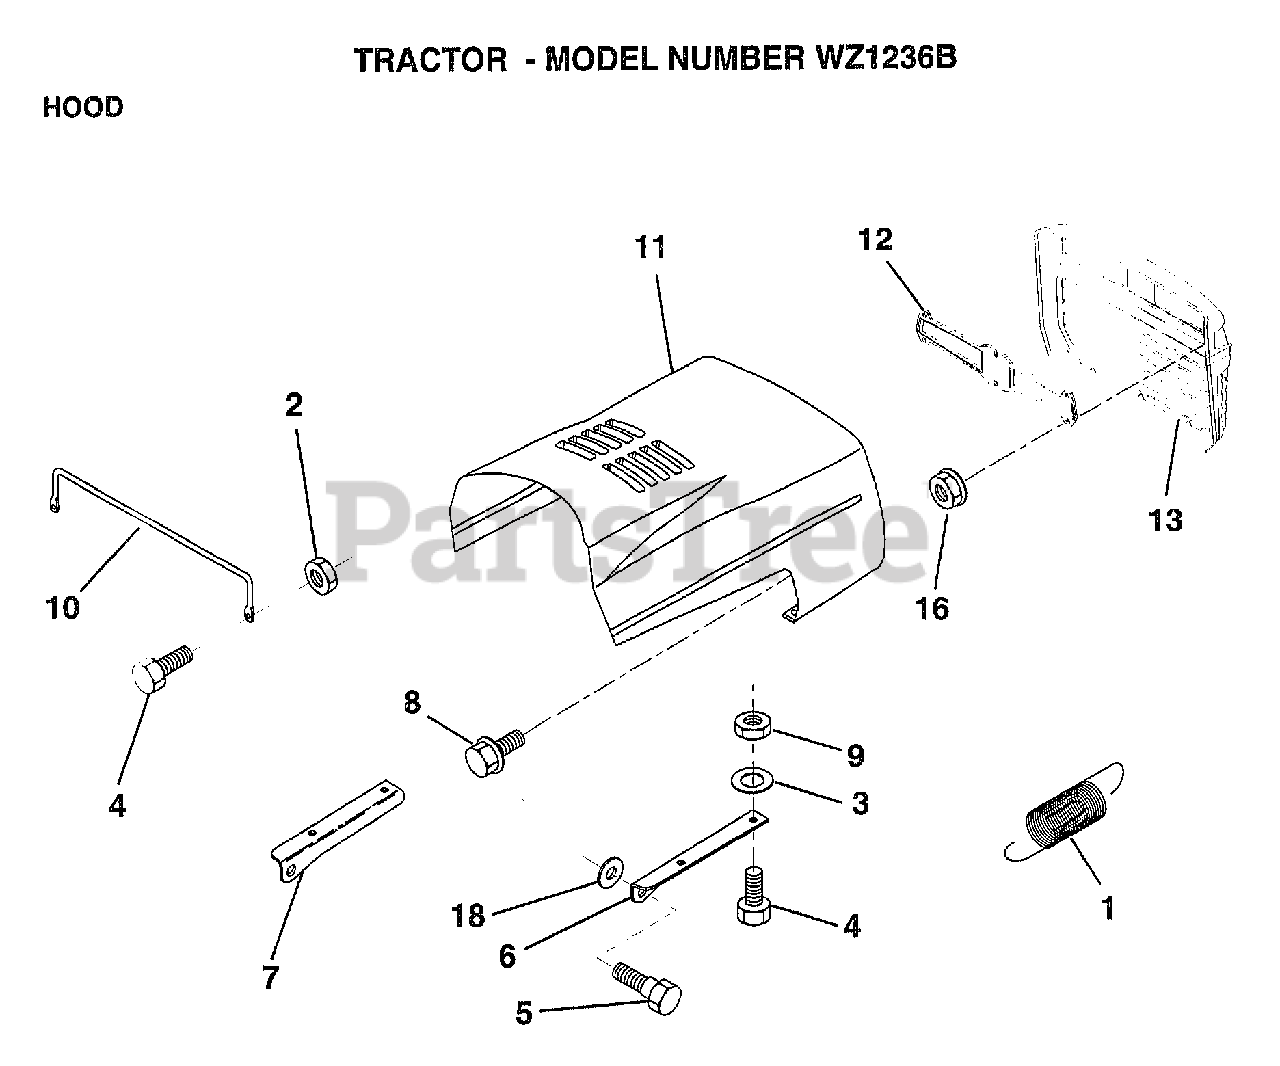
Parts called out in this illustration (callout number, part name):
1	EXT SPRING
2	NUT
3	WASHER
5	BOLT.SHLD.5/16-18
6	BRKT HOOD RH
7	BRKT HOOD LH
8	"SCREW,HWHD.HI-LO#13-16X3/4"
9	NUT
10	"BRACE,HOOD"
11	HOOD
13	GRILL (BLACK)
16	NUT
18	WASHER
